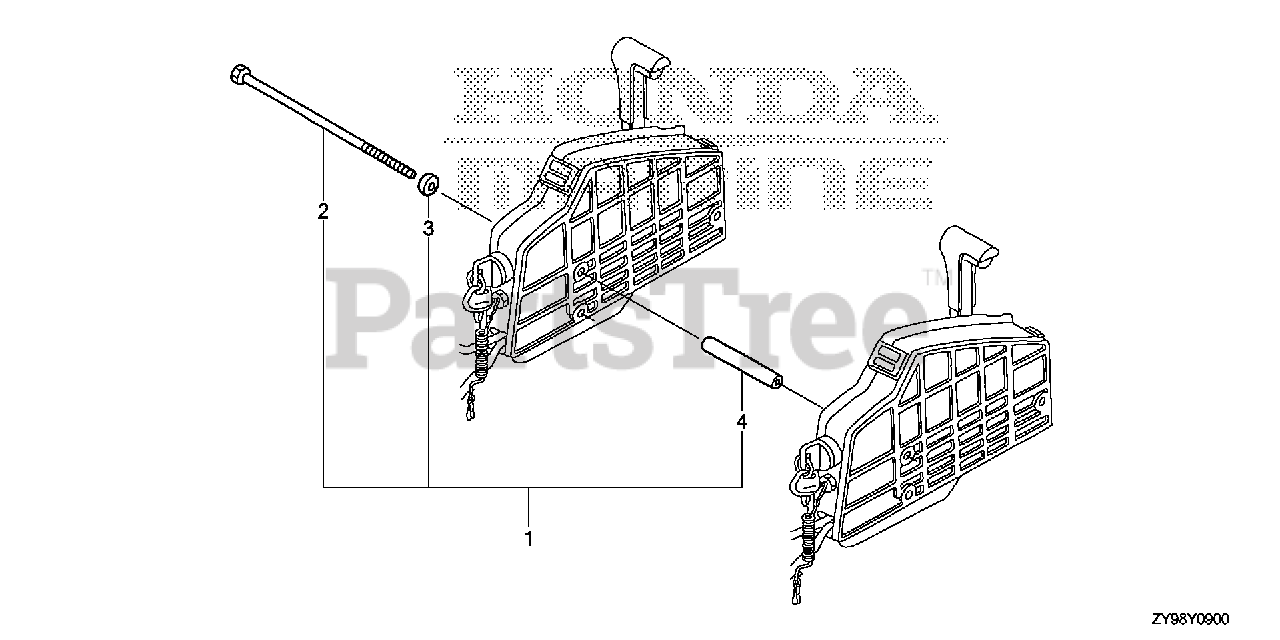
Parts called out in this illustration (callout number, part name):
1	BOLT KIT, SIDE REMOTE CONTROL
2	BOLT, SPECIAL (6X220)
3	COLLAR, DISTANCE (A)
4	COLLAR, DISTANCE (B)
